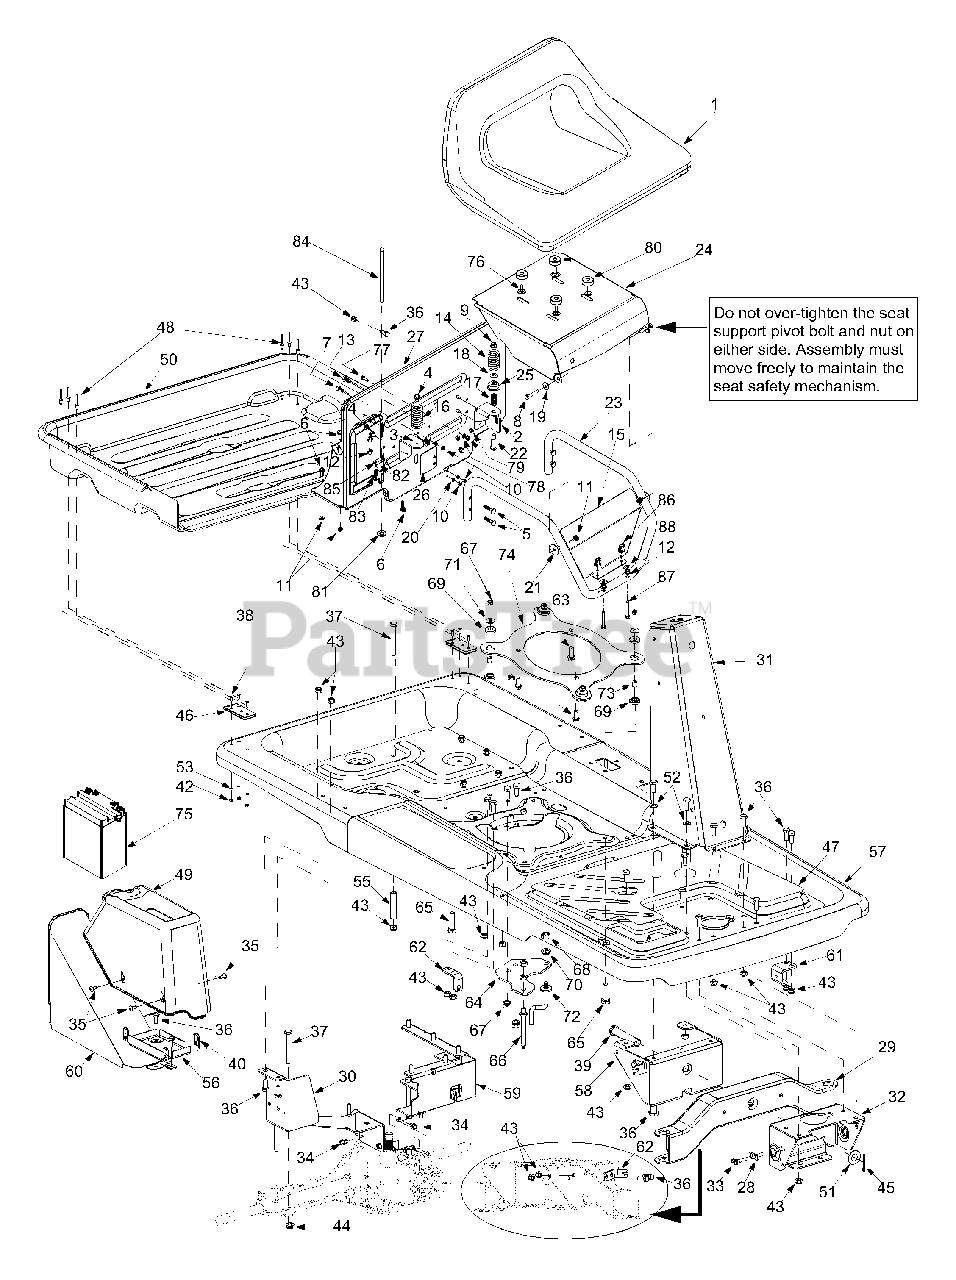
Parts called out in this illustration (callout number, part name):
1	Seat: Black, Low Back
5	Carriage Bolt 5/16 x 1.5"
6	Hex Bolt M8-1.25: 20
7	Special Screw M6-1: 16
8	Hex Bolt M8-1.25: 45
9	Flange Lock Nut 3/8-16
10	Hex Nut M6-1
11	Hex Lock Nut M8-1.25
12	Flange Lock Nut 5/16-18
13	Ratchet Clip
14	Compression Spring
17	Compression Spring
18	Bell Washer .375 x .870 x .063
19	Shoulder Bushing
20	Lock Washer
21	Flat Washer 8.4 x 35
22	Shoulder Screw
26	Bag Switch Cover
27	Seat Support Bracket
28	Switch Plate
34	TT Screw 1/4-20 x 0.5"
35	Machine Screw
36	Hex Screw M8-1.25: 20
37	Special Screw
38	Special Screw
39	Clevis Pin
40	Speed Nut 1/4-20
42	Hex Nut
43	Hex Lock Nut
44	Flange Lock Nut
45	Cotter Pin
46	Tray Hinge
47	Foot Pad
49	Battery Cover
50	Bag Tray
51	Flat Washer .64 x 1.24 x .06
52	Flat Washer 8.4 x 16
53	Lock Washer M4
55	Spacer
62	Cable Bracket
63	TT Sems Screw 3/8-16 x 1.0
64	Belt Keeper Bracket
65	Hex Bolt M8-1.25: 30
66	Pin: Belt Guard
67	Lock Nut M8-1.25
68	Hex Nut 5/16-18
69	Engine Mount: Gromm.
70	Lock Washer 5/16
71	Flat Washer 8.4 x 24
72	Belt Keeper Rod
73	Spacer
76	Self-Tapping Screw 3/8-16 x 1.250
77	Self-Tapping Screw 1/4-20 x 0.75
78	Lock Washer
79	Hex Sems Nut 1/4-20
80	Spacer
81	Speed Nut
82	Bag Hinge Bracket
83	Torsion Spring
84	Hinge Pin
85	Bag Chute Door Assembly
86	Wing Nut
87	Hex Bolt 5/16-12 x 2.0
88	Flat Washer
